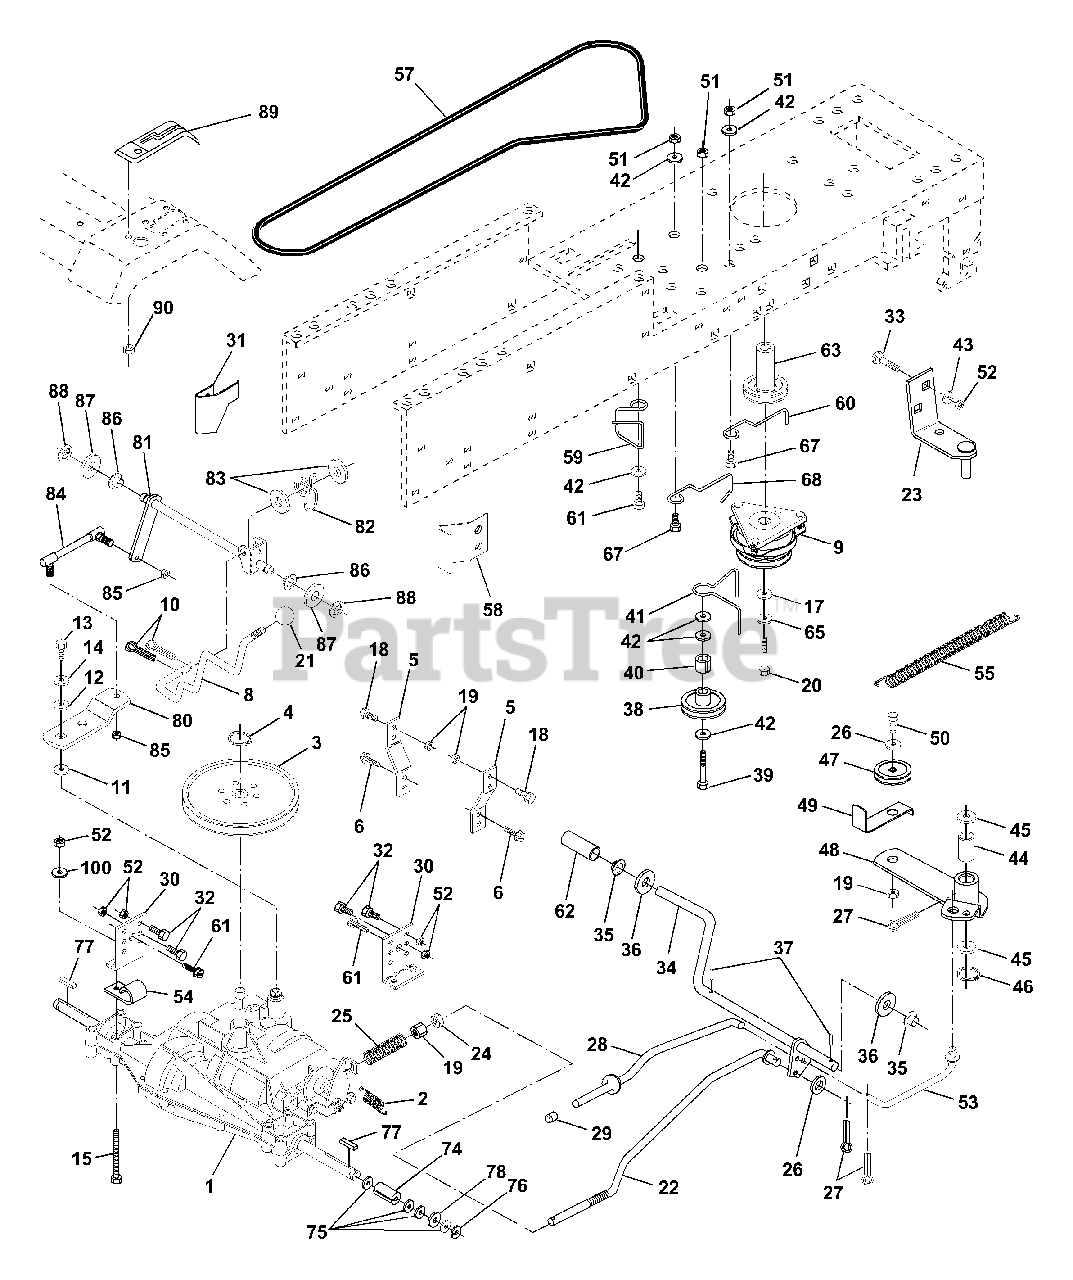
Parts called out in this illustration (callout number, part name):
1	Transaxle 6sp Dana LT Model #4360-81
2	Spring Return Brake T/a Zinc
3	Pulley Transaxle 20"tires
4	Ring Retainer # 5100-62
5	Strap Torque 30 Degrees
6	Screw Thdrol 5/16-18 X 3/4 TYT
8	Rod Shifter
9	Clutch Electric
10	Pin Cotter 1/8 X 1 Cad
11	Washer Plate Shf 388 Sq Hole
12	Washer 15/32 X 3/4 X 16 Ga
13	Bolt Fin Hex 1/4-28unfx3/4 Gr8
14	Washer Lock Hvy Helical 1/4
15	Bolt Fin Hex 5/16-18uncx 2 3/4
16	Nut Lock H w/insert 5/16-18
17	Washer 1-1/2 OD X 15/32 ID X .250
18	Bolt Fin Hex 3/8-16unc X 1 Gr. 5
19	Nut Lock 3/8-16 Unc
21	Knob Duckhead 3/8-16unc Blk
22	Rod Brake Blk Zinc 27 326
23	Bracket Asm. Clutch
24	Nut Hex Jam 3/8-16 Unc
25	Spring Rod Brake 2 00 Zinc
26	Washer 13/32 X 13/16 X 16 Ga
27	Pin Cotter 1/8 X 3/4 Cad
28	Rod Brake Parking 14 500
29	Cap Brake Parking Black
30	Bracket Mtg Transaxle
31	Keeper Belt LH LT 14 Ga
32	Bolt Hex Hd 5/16-18unc X 3/4
33	Bolt, Carriage 5/16-18 x 3/4
34	Shaft Asm Pedal Foot 1 930
35	Bearing Nylon Blk 629 Id
36	Washer 21/32 X 1 X 16 Ga
37	Pin Roll 3/16 X 1"
38	Pulley Idler Flat
39	Bolt Fin Hex 3/8-16unc X 2-3/4
40	Spacer Split 395 X 59 Bzp
41	Keeper Belt Retainer
42	Washer 13/32 X 13/16 X 12 Ga
43	Washer 11/32 x 5/8 x 12 Ga.
44	Bearing Nyl 503 X 628 X 1 25
45	Washer Hardened
46	Ring Klip #t5304-50
47	Pulley Idler V Groove Plastic
48	Bellcrank Asm Clutch
49	Retainer Belt Style Spring
50	Bolt Hex Hd 3/8-16unc X 1-1/2
51	Nut Crownlock 3/8-16 Unc
52	Nut Crownlock 5/16 - 18
53	Link Clutch 7 66
54	Clip Fuel Line 13/32 Mtg. Hole
55	Spring Return Clutch 6 75
57	V-Belt Ground Drive 95 25 42"
58	Keeper Belt RH LT Pnt/zinc 16g
59	Keeper Belt Chassis Span Ctr
61	Screw Thdrol 3/8-16x3/4 Ty-tt
62	Cover Pedal Premuim
63	Engine Pulley LT/YT
64	Bolt, Hex 7/16-20 x 4-1/4
65	Washer Lock Hvy Hlcl Spr 7/16
66	Keeper Belt Engine LH LT
67	Bolt Fin Hex 3/8-16unc X 1
70	Keeper Belt Engine BZP Zinc
74	Spacer Split
75	Washer 25/32 X 1 1/4 X 16 Ga
76	E-ring #5133-75
77	Key Square 2 0 X 1845/ 1865
78	Washer 25/32 X 1-5/8 X 16 Ga
80	Arm Shift Transaxle
81	Shaft Asm Cross 20"t 42"deck
82	Spring Torsion T/a
83	Washer 17/32 X 3/4 X 16 Ga
84	Rod Tie Shift Adj Ball
85	Nut Nylock 1/4-28
86	Bushing Rod Strg 629/632 Id
87	Washer 21/32 X 1-1/4 X 16 Ga
88	Ring Klip #5304-62
89	Console Shift 6sp W/ign LT
90	Nut Self-thd wsh-hd 1/4 zinc
100	Washer 11/32 x 3/4 x 16 Ga.
